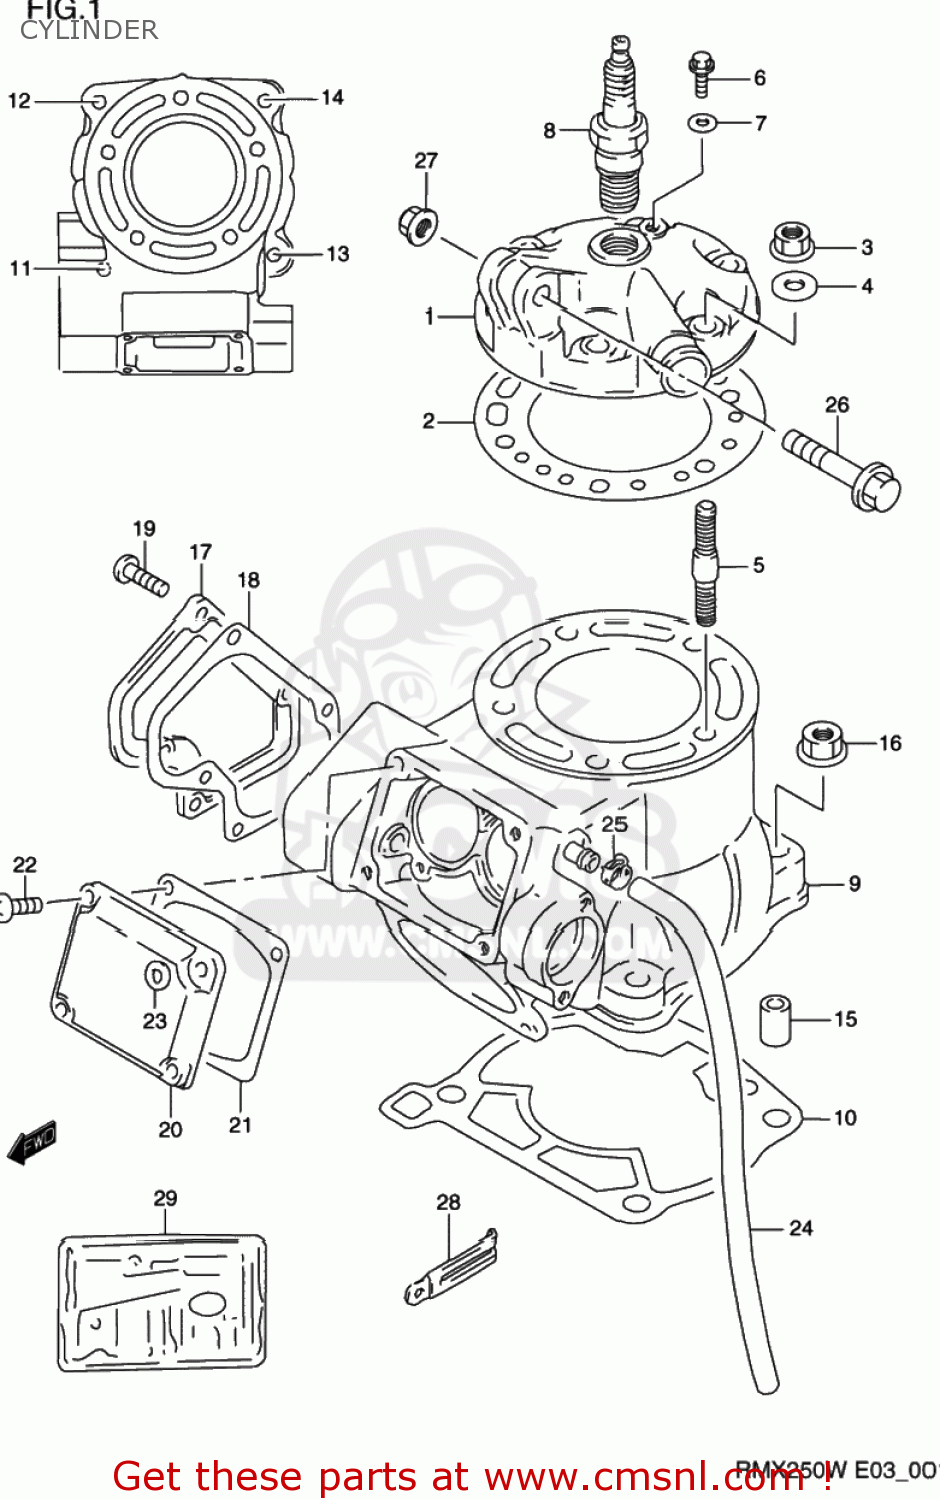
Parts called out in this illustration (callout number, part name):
1	HEAD,CYLINDER
2	GASKET,CYLINDER HEAD
3	NUT
4	WASHER(8.5X19X2.3)
5	BOLT,STUD
6	UNION
7	GASKET(6.2X11X1).2 (NAS)
8	SPARK PLUG BR9EV
9	CYLINDER SET
10	GASKET,CYLINDER (NAS)
11	STUD 10X30
12	STUD BOLT
13	STUD BOLT (L:40)
14	BOLT,STUD
15	PIN(13X10.4X20)
16	NUT
17	COVER,CYLINDER NO.1
18	GASKET,CYL COVER NO.1 (NAS)
19	BOLT
20	COVER,CYLINDER NO.2
21	GASKET,CYLINDER COVER NO.2 (NAS)
22	SCREW
23	GASKET(5.3X9.3X1.2) (NAS)
24	HOSE
25	CLIP
26	BOLT(8X45)
27	NUT
28	CLAMP(L:45)
29	GASKET SET (NAS)
